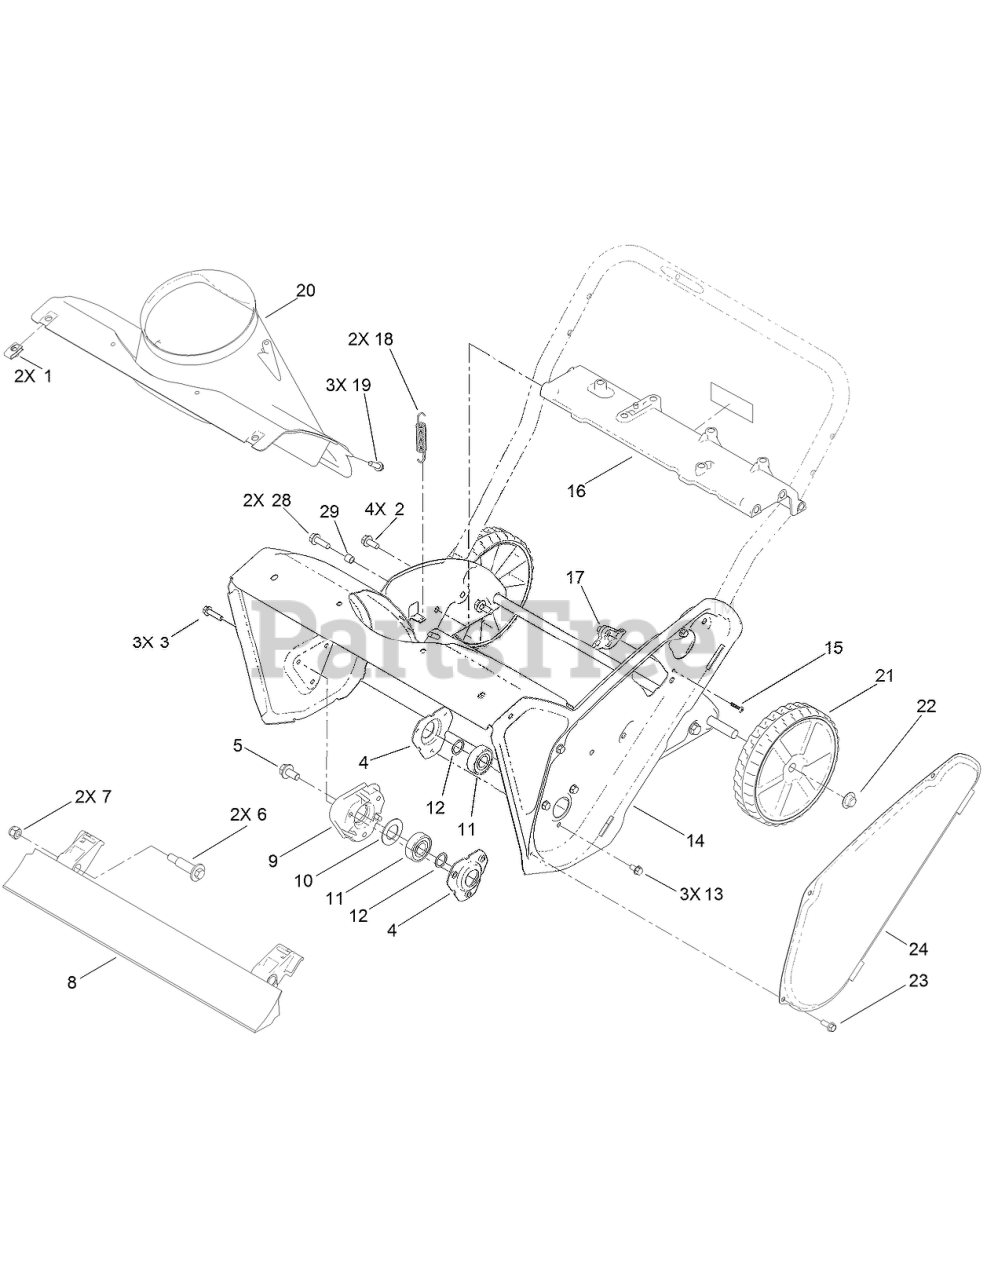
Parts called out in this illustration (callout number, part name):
2	SCREW-HWHTF
3	SCREW-HWHTF
4	FLANGE-BEARING
5	SCREW-HWH
6	BOLT-WHEEL
7	NUT-LOCK, NI
8	BLADE-SCRAPER
9	SPACER-BEARING, RH
10	WASHER-RUBBER
11	BEARING-BALL
12	WASHER-THRUST
13	SCREW-HWH
14	HOUSING-AUGER
15	SCREW-PPH
16	BRACE-FRAME
17	GUIDE-CABLE, CLUTCH
18	SPRING-EXTENSION
19	SCREW-HWH
20	CHUTE-LOWER
21	WHEEL ASM
22	NUT-PUSH
23	SCREW-HWH
24	COVER-BELT
28	SPACER
29	SCREW-HWHTF
